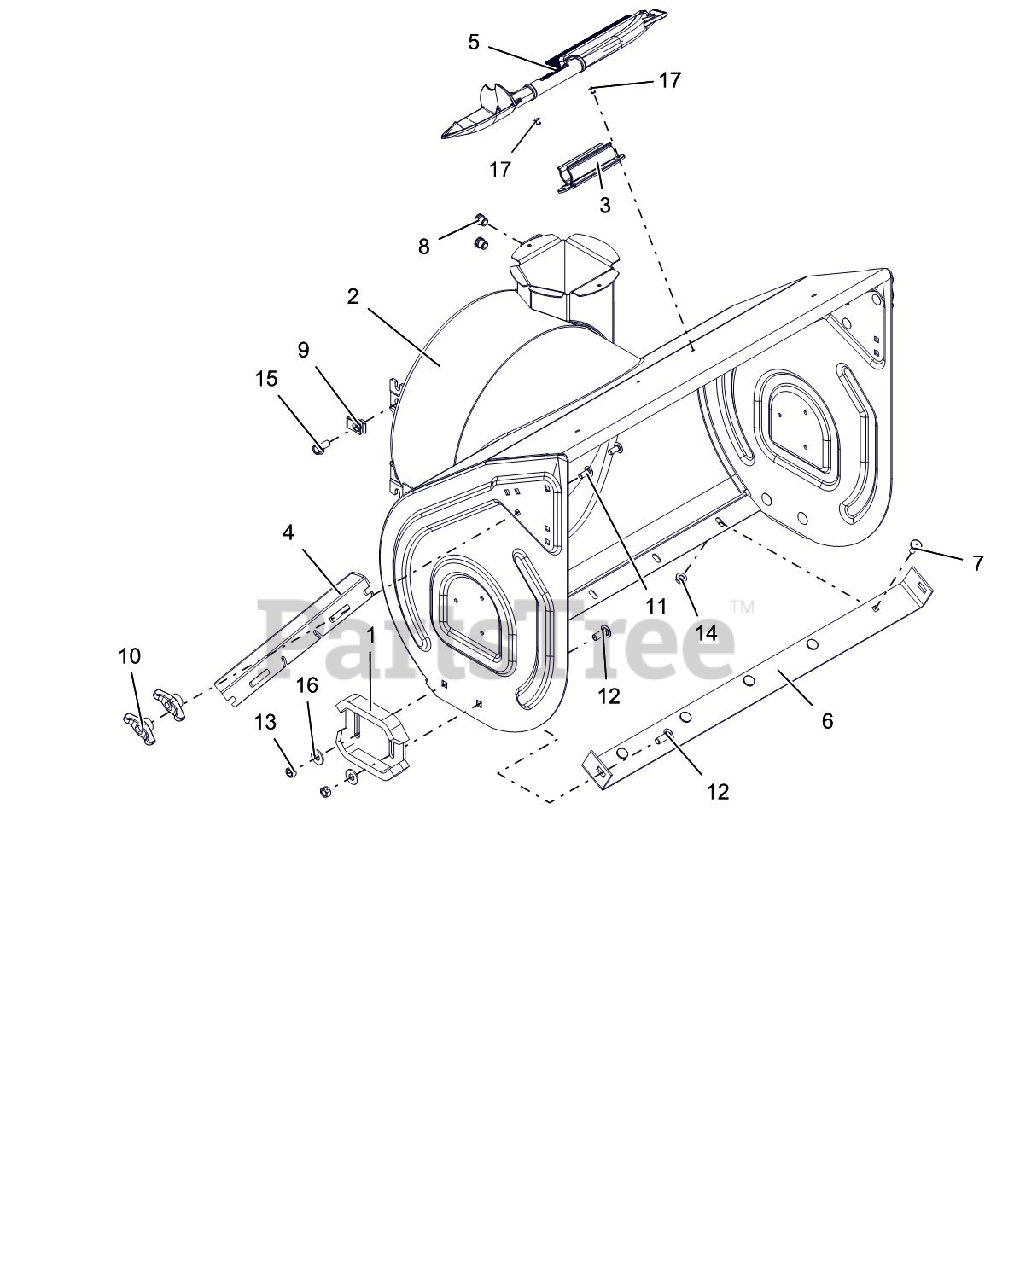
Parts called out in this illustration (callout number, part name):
1	RUNNER, SKID SHOE
2	BLOWER HOUSING W/DECAL 28"
3	MOUNT, SNOW CLEAN OUT
4	CUTTER, DRIFT
5	DEVICE, SNOW CLEAN OUT W/BRUSH
6	BLADE, SCRAPER-28"
7	BOLT, MODIFIED HEAD CARRIAGE
8	NUT, THREADED INSERT .38-16
9	NUT-RTNR .375-16X.37
10	KNOB,WING .31-18 UNC NYL/TALC
11	@BLT-RHDSSQNK .31-18X.75 G5YZ
12	@BLT-RDHDSHSQNK.38-16X1.0 G5YZ
13	@NUT-LK-CTR .38-16 YWZC
14	@NUT-LK-TOP-FLG .31-18 YWZC
15	BLT-SERHFWH .38-16X.75 YWZC
16	@WSHR-FL-STL.438X1.00X.083 YWZ
17	RVT-POP .187 YZ
